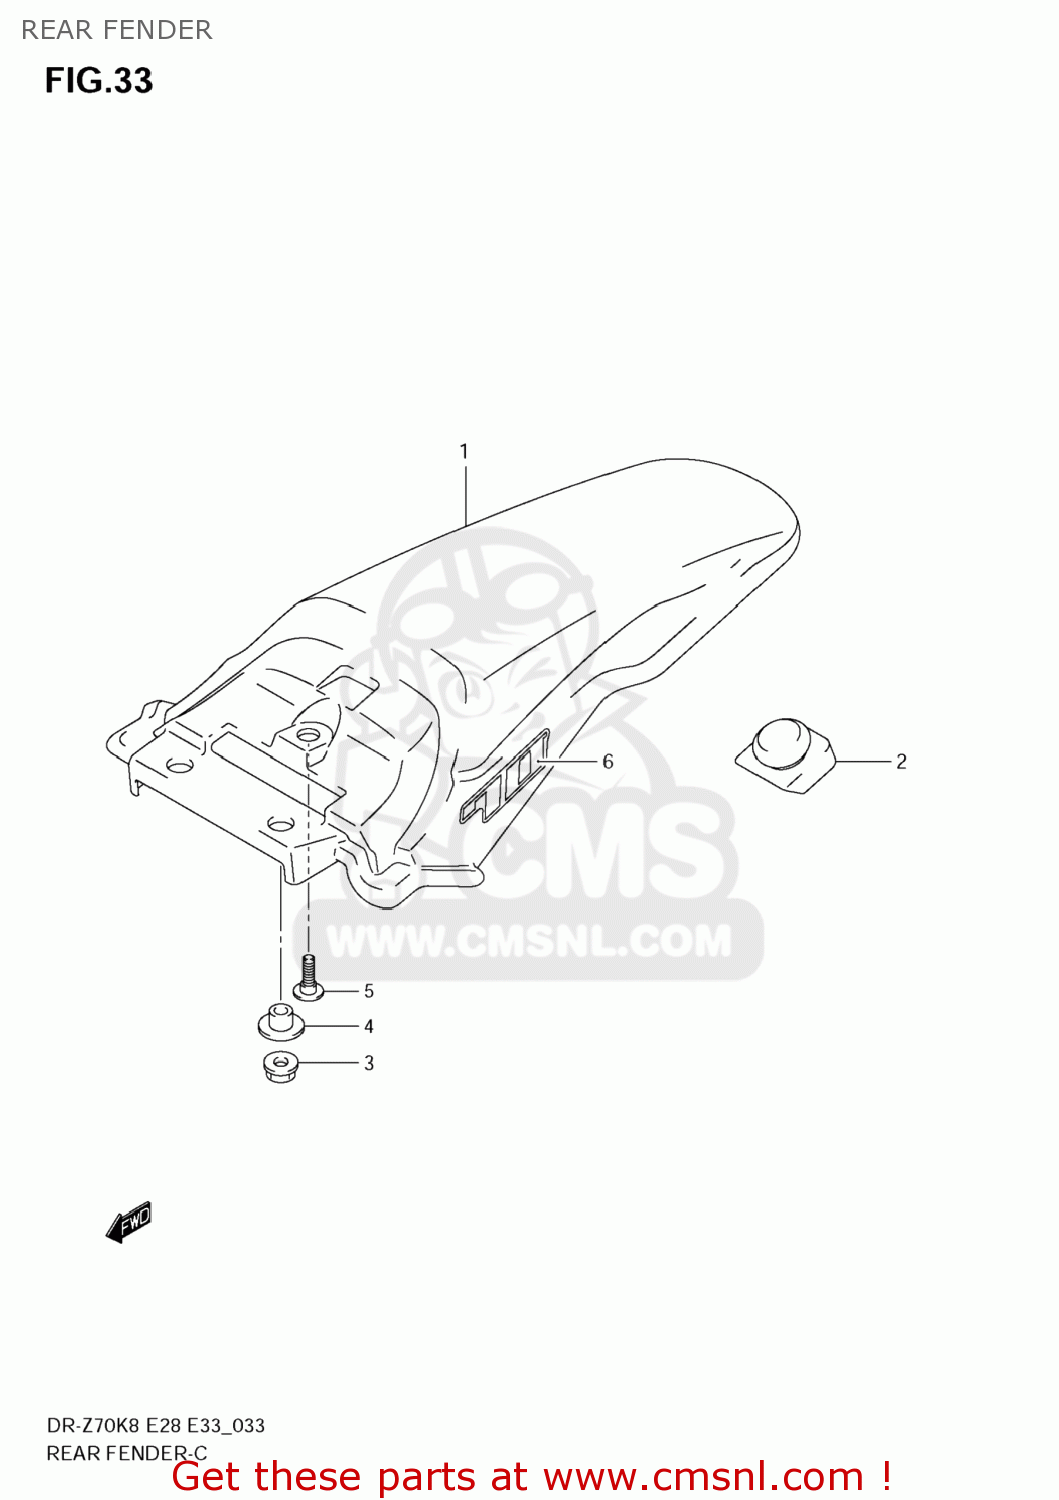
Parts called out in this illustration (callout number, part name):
1	FENDER,RR
2	CUSHION,RR FENDER
3	NUT
4	SPACER(6.2X8.4X6.9)
5	SCREW
6	EMBLEM,RR FENDER
